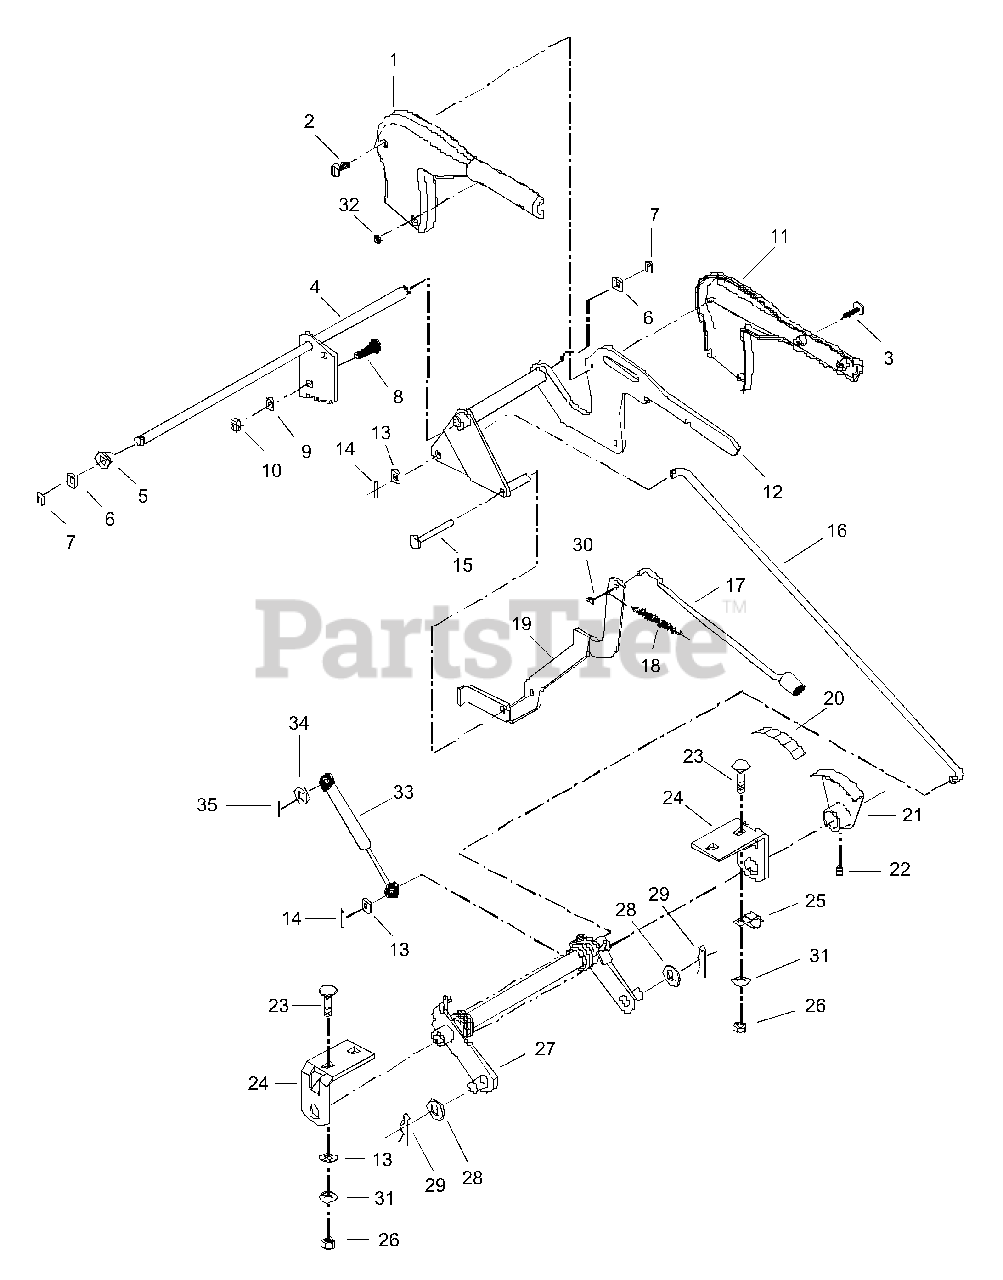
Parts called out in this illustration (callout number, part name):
1	Cover-Lift Right Hand
2	Screw-Tapping 12-16 x 1.125
3	Screw-Machine .10-24 x .75
4	Pivot-Lift Lever
5	Bushing-Flange .508 x .873
6	Washer-Flat-Steel .520 x .827 x .062
7	Ring-Retaining-External .500 x .460
8	Bolt-Round Head Square Neck .31-18 x .75 Grade 5
9	Washer-Flat-Steel .323 x .625 x .062
10	Nut-Locking-Center .312-18
11	Cover-Lift Left Hand
12	Lever-Lift
13	Washer-Flat-Steel .406 x .812 x .065
14	Pin-Cotter .12 x 1.0
15	Pivot-Pin
16	Lift-Link
17	Pin-Lift
18	Spring-Tension .048 x .44 x 2.12
19	Lever-Detent
20	Decal-Indicator 5 Position
21	Indicator-Deck Height
22	Screw-Set .25-20 x .25
23	Bolt-Round Head Square Neck .38-16 x .75
24	Center Lift Bracket
25	J-Clamp
26	Nut Hex .375-16
27	Center Lift Lever
28	Washer-Flat-Steel .630 x 1.005 x .062
29	Pin-Hair External .12 x .31 x 2.37
30	Ring-Retaining-External .250 x .010
31	Washer-Lock .375 x .094
32	Nut-Locking-Nylon 10-24
33	Spring-Compression .315 x .75
34	Washer-Flat-Steel .38 x .875 x .083
35	Pin-Cotter .12 x .75
